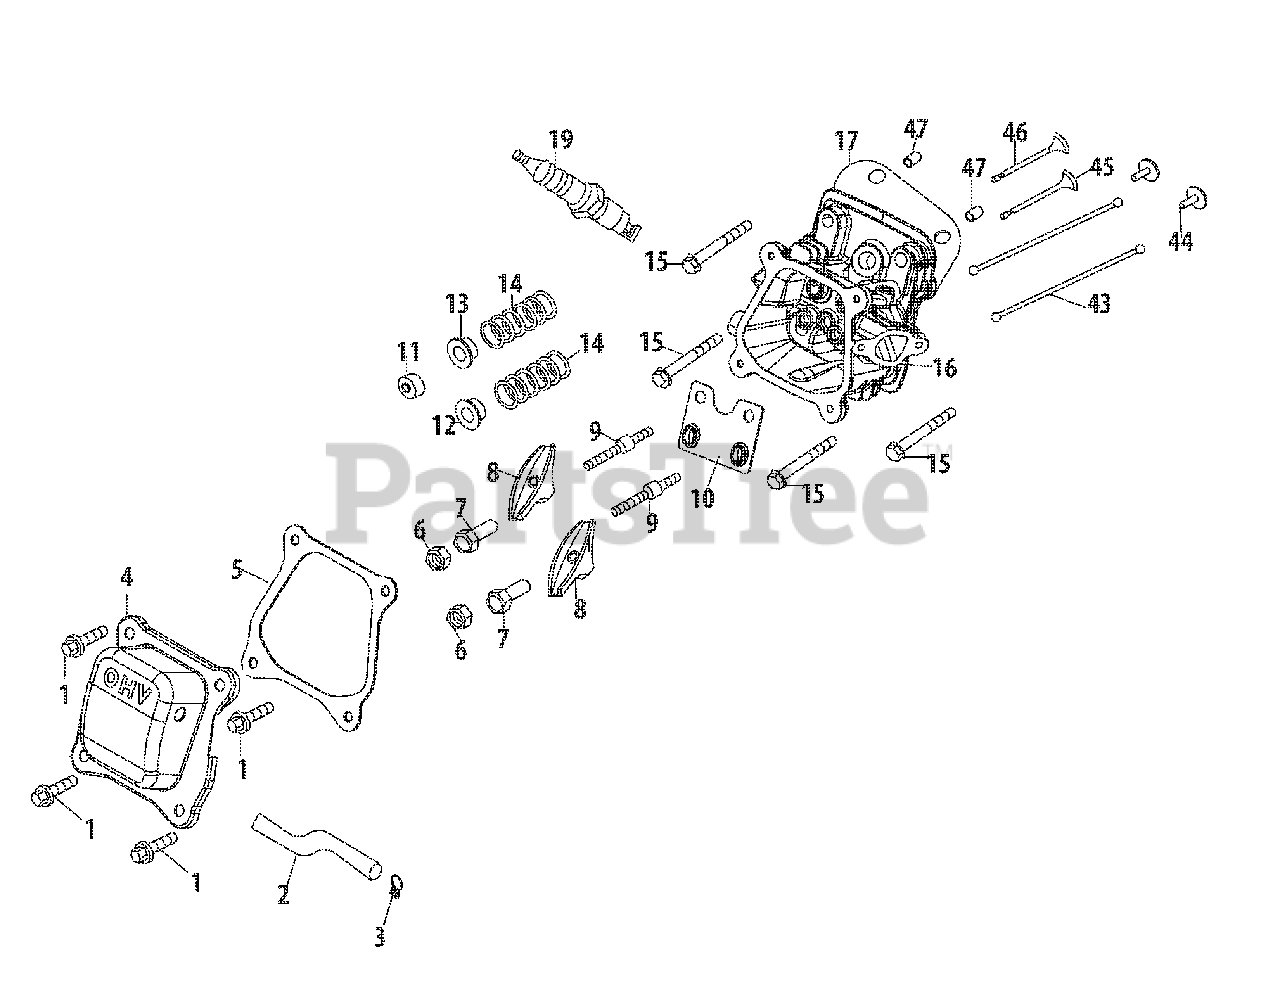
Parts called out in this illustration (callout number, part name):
1	Bolt M6×16
2	Hose - Breather
3	Clamp - Breather Hose
4	Valve Cover
5	Valve Cover Gasket
6	Pivot Locking Nut
7	Valve Adjusting Nut
8	Rocker Arm
9	Rocker Arm Stud
10	Push Rod Guide
11	Rotator,Exhaust Valve
12	Intake Valve Spring Seat
13	Exhaust Valve Spring Seat
14	Spring Valve
15	Bolt M8×50
16	Cylinder Head
17	Gasket,Cylinder Head
19	Spark Plug
43	Push Rod
45	Intake Vavle
46	Exhaust Vavle
47	Dowel Pin 10×16
